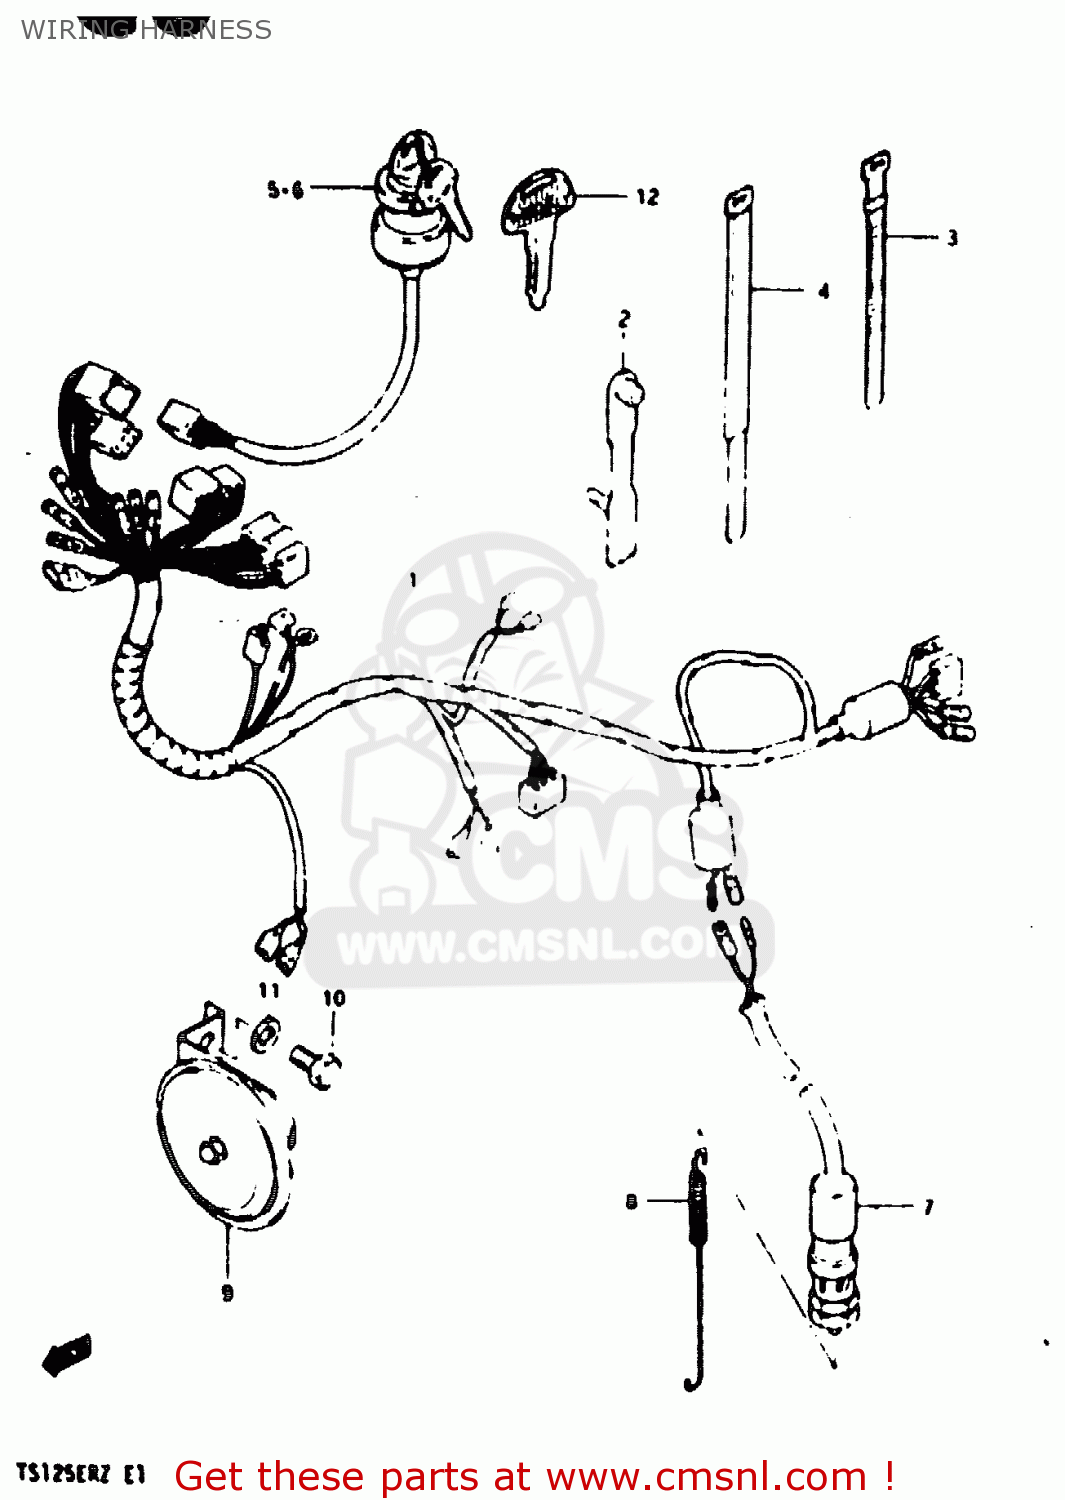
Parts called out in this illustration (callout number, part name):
1	WIRING HARNESS
2	CLAMP,L:88
3	CLAMP(L:120)
4	CLAMP
6	SWITCH, IGNITION
7	SWITCH ASSEMBLY,STOP LAMP
8	SPRING
9	HORN ASSY
10	BOLT
11	WASHER
12	KEY,BLANK
